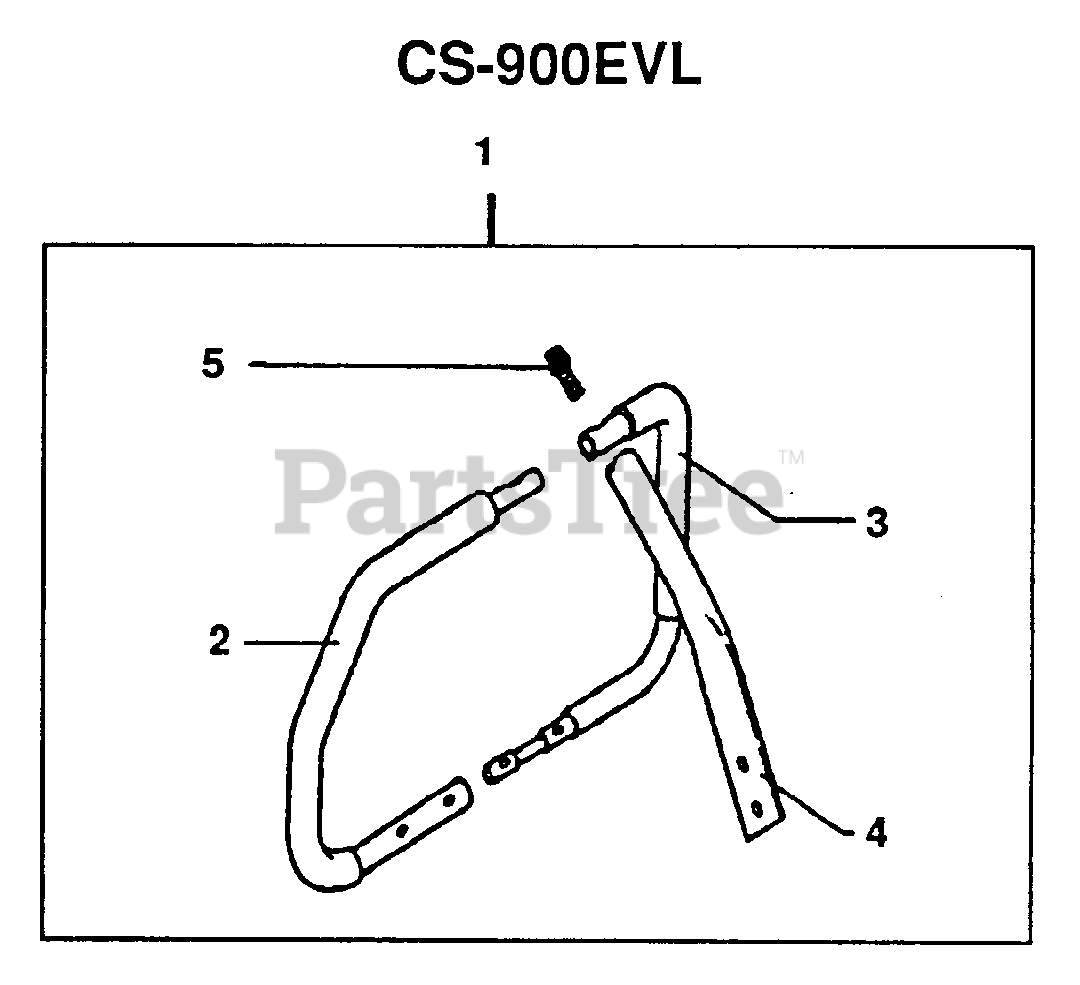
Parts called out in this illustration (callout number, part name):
1	HANDLE KIT
2	HANDLE - LEFT
3	HANDLE - RIGHT
5	SCREW - 5X20
